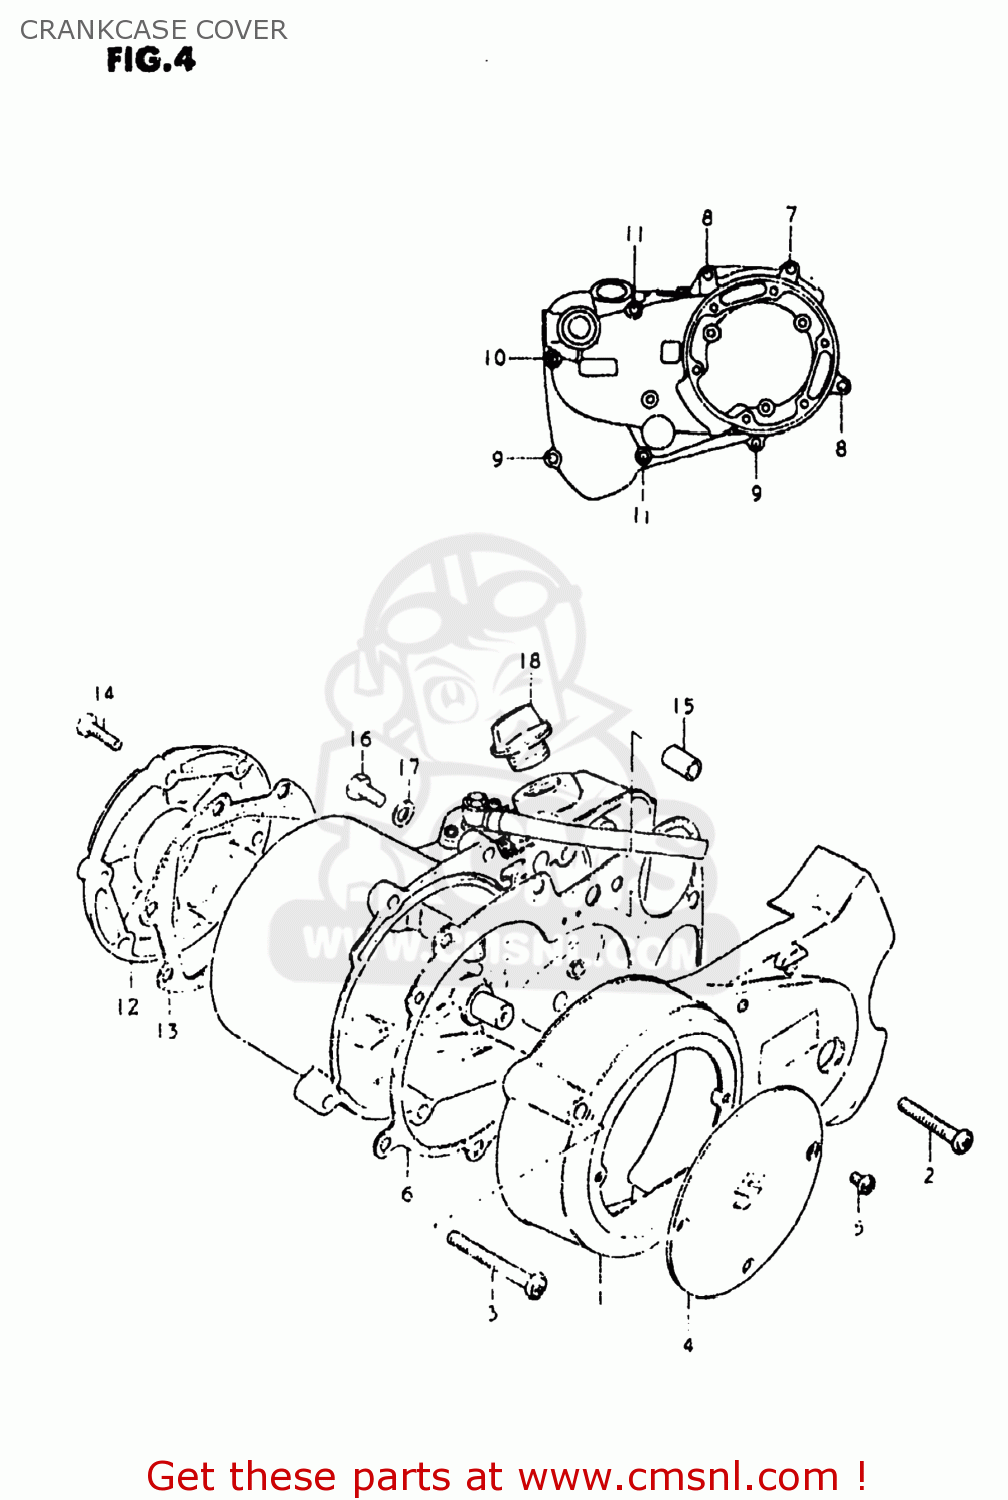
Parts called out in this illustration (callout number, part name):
1	COVER,MAGNETO
2	SCREW (6X35)
3	SCREW (6X45)
4	CAP,MAGNETO INSPECTION
5	SCREW 4X6
6	GASKET,CLUTCH COVER (MCA)
7	SCREW
8	SCREW
9	SCREW 6X30
10	SCREW (6X45)
11	SCREW
12	CAP,CLUTCH RELEASE ADJUST
13	GASKET,CLUTCH RELEASE ADJUSTER CAP (NAS)
14	SCREW
15	PIN
16	SCREW(6X10)
17	GASKET(6.2X11X1) (NAS)
18	PLUG,OIL FILTER
